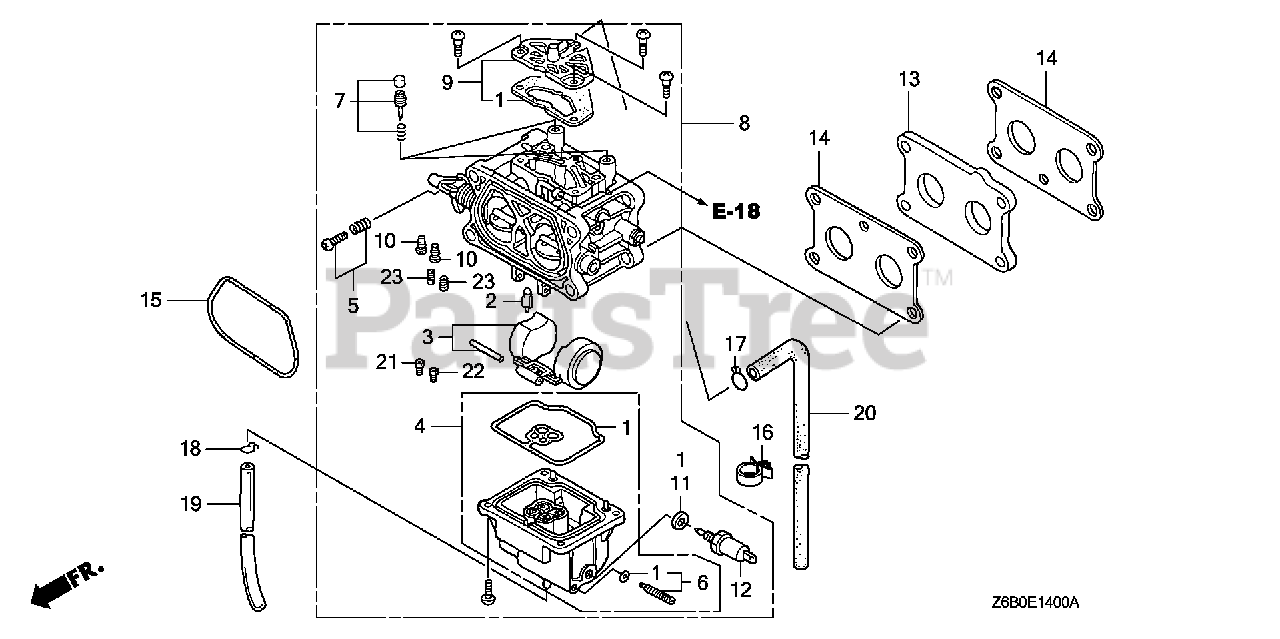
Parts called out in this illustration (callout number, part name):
1	GASKET SET
2	VALVE, FLOAT
4	CHAMBER SET, FLOAT
6	SCREW SET, DRAIN
7	SCREW SET, PILOT
8	CARBURETOR ASSY. (BW02B C)
9	COVER SET, AIR VENT
12	VALVE ASSY., SOLENOID
13	INSULATOR, CARBURETOR
14	GASKET, INSULATOR
15	GASKET, AIR CLEANER
16	CLIP, WIRE HARNESS
17	CLIP, TUBE (B8)
18	CLIP, TUBE (B6.5)
19	BULK HOSE, VINYL (4X7X8000) (4X7X300)
20	BULK HOSE, VACUUM (4.5X1000) (4.5X400)
21	JET, MAIN (#82.5)
21	JET, MAIN (#85)
21	JET, MAIN (#87.5)
22	JET, MAIN (#85)
22	JET, MAIN (#87.5)
22	JET, MAIN (#90)
23	JET, PILOT (#37.5)
